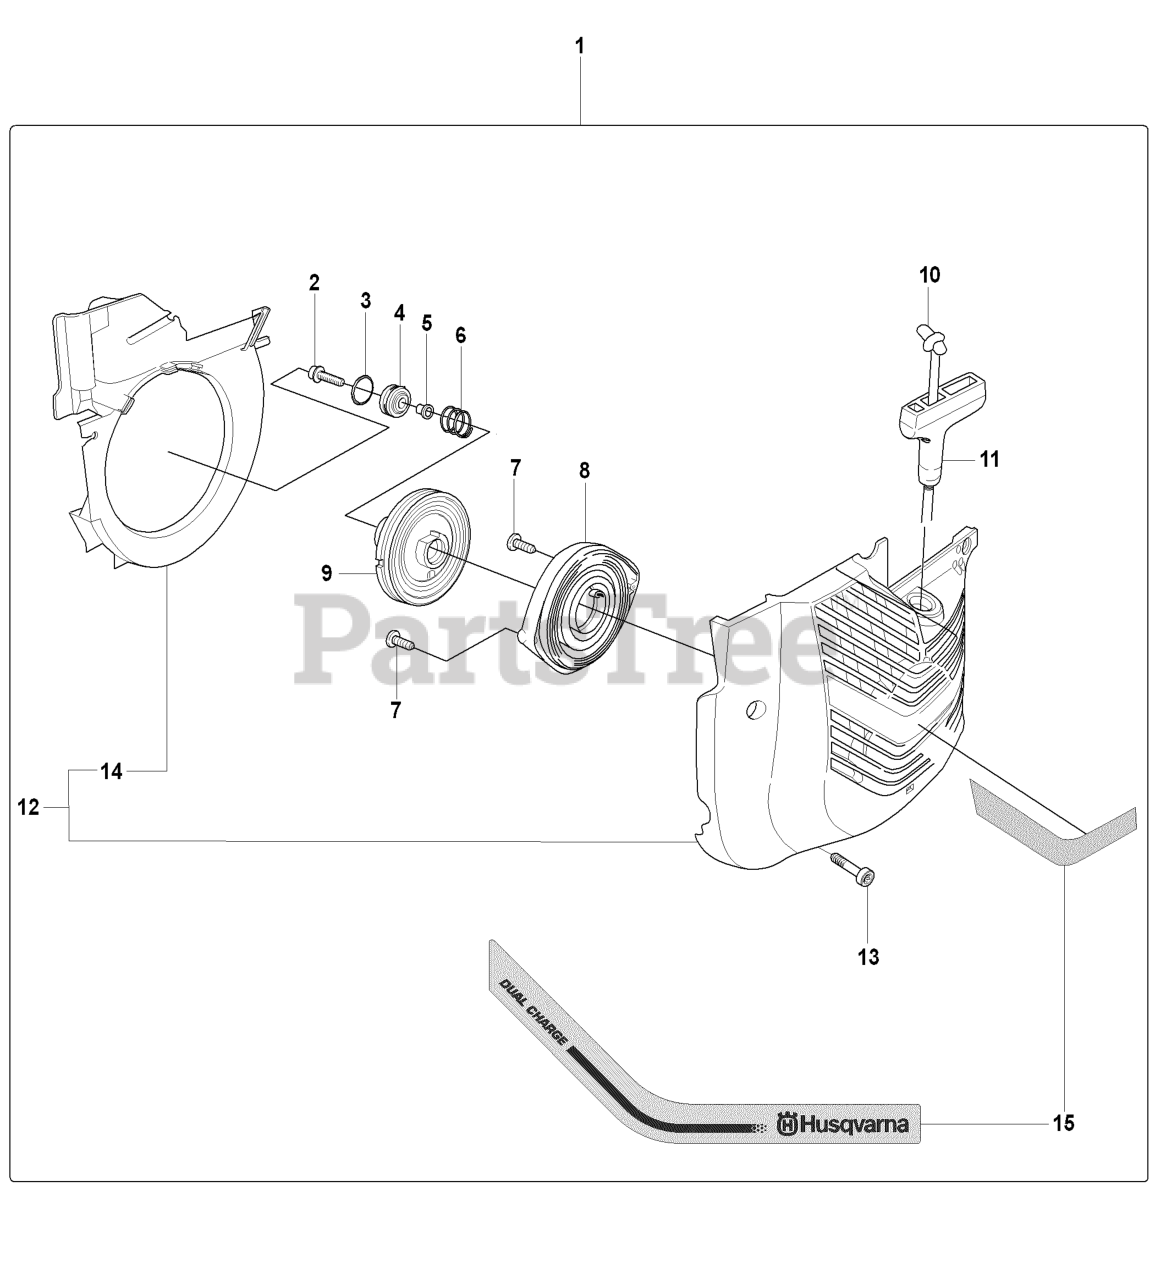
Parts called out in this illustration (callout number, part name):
1	%STARTER
2	SCREW
4	RP WASHER
8	RETURN SPRING
9	STARTER PULLEY
10	STARTER ROPE
10	STARTER ROPE 50 M
11	STARTER HANDLE
12	STARTER COVER
14	RP COOLING AIR CONDUCTOR
